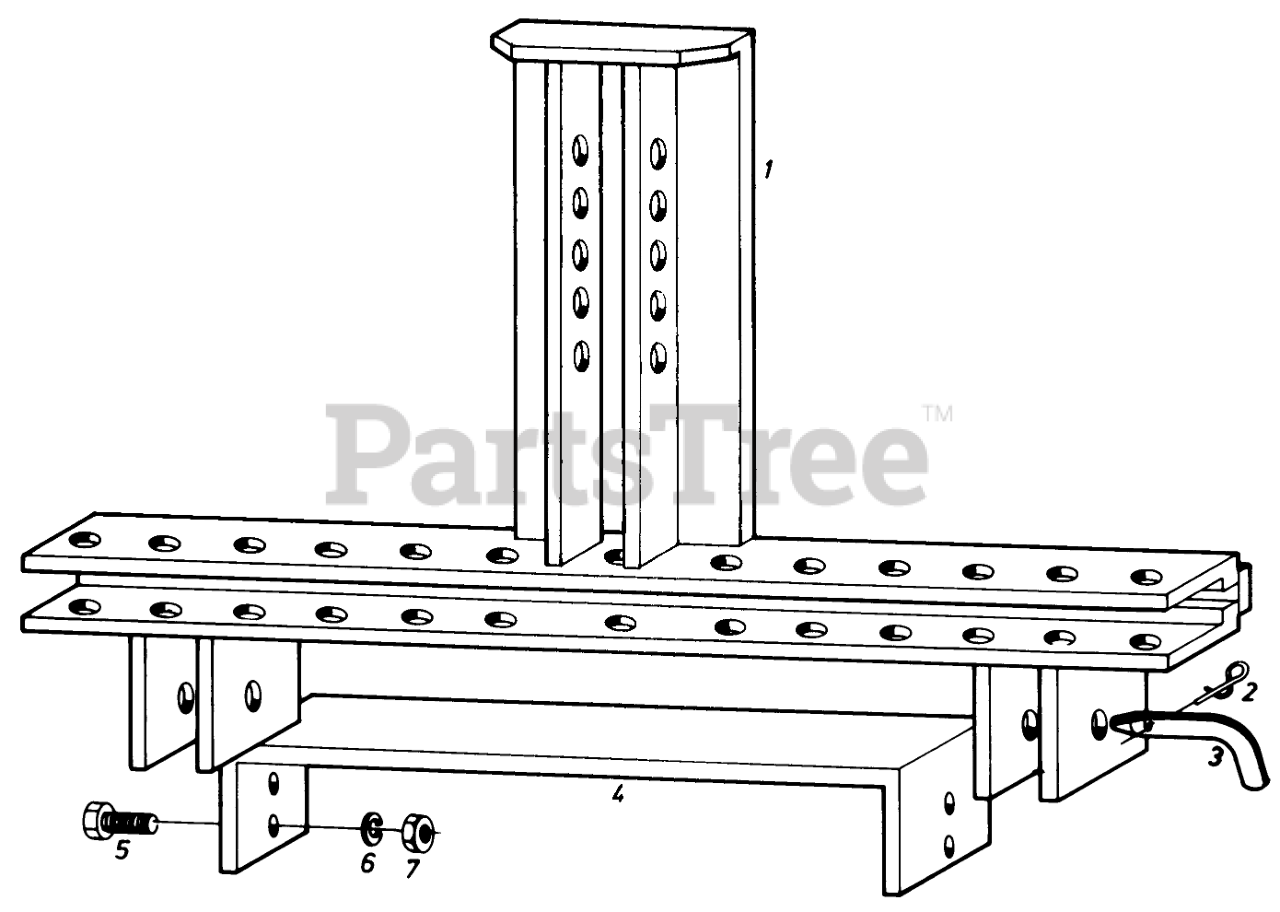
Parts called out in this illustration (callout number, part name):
1	Tool Bar
2	Hairpin Cotter
3	"L" Shaped Clevis Pin
4	Stabilizer
6	Lockwasher
